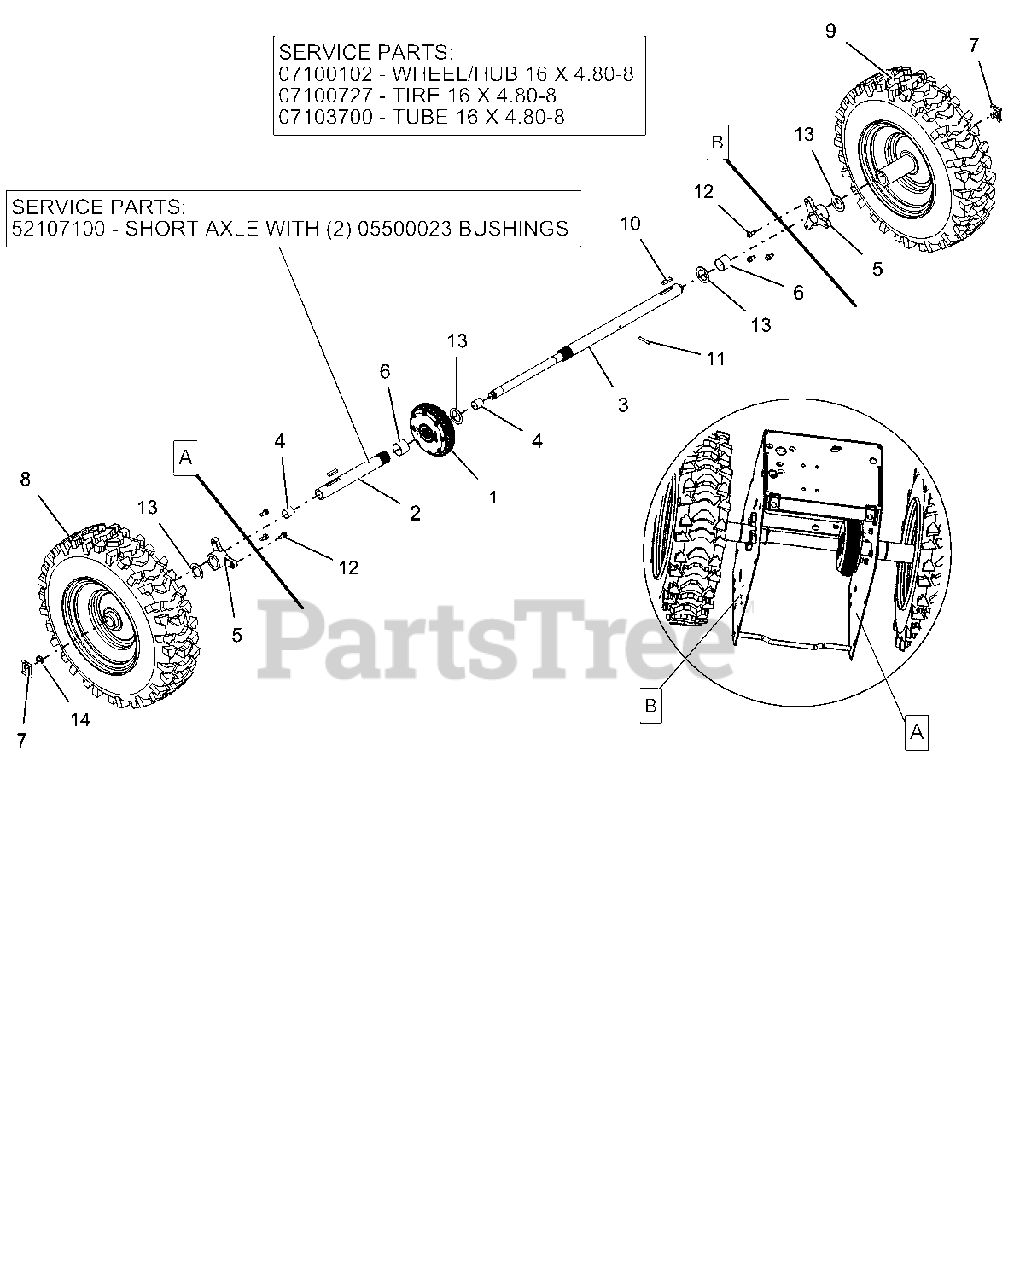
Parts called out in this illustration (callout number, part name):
1	DIFFERENTIAL, AUTOMATIC
2	BSHG-SLV .706X.764X.75 BRZ
2	KIT, SHORT AXLE W/BUSHINGS
3	AXLE, LONG - DIFFERENTIAL
4	BSHG-SLV .706X.764X.75 BRZ
5	BUSHING, AXLE
6	BSHG-SLV, 1.012X1.125X.875
7	CLIP, SNAP .625 DIA
8	TIRE/WHEEL,RH 16X4.8-8 DIFF T2
9	TIRE/WHEEL,LH 16X4.8-8 DIFF T2
10	KEY-RECT .25X.188X1.00
11	PIN-ROLL .188X1.25
12	SCR-TAP .25-20X.50 HWH TR YWZ
13	WSHR-FL-STL 1.010X1.505X.062YZ
14	RG-RTNG-EXT .625X.042
15	HUB, WHEEL - 16X4.8-8 DIFF
16	TIRE, 4.80-8 K478
17	TUBE
